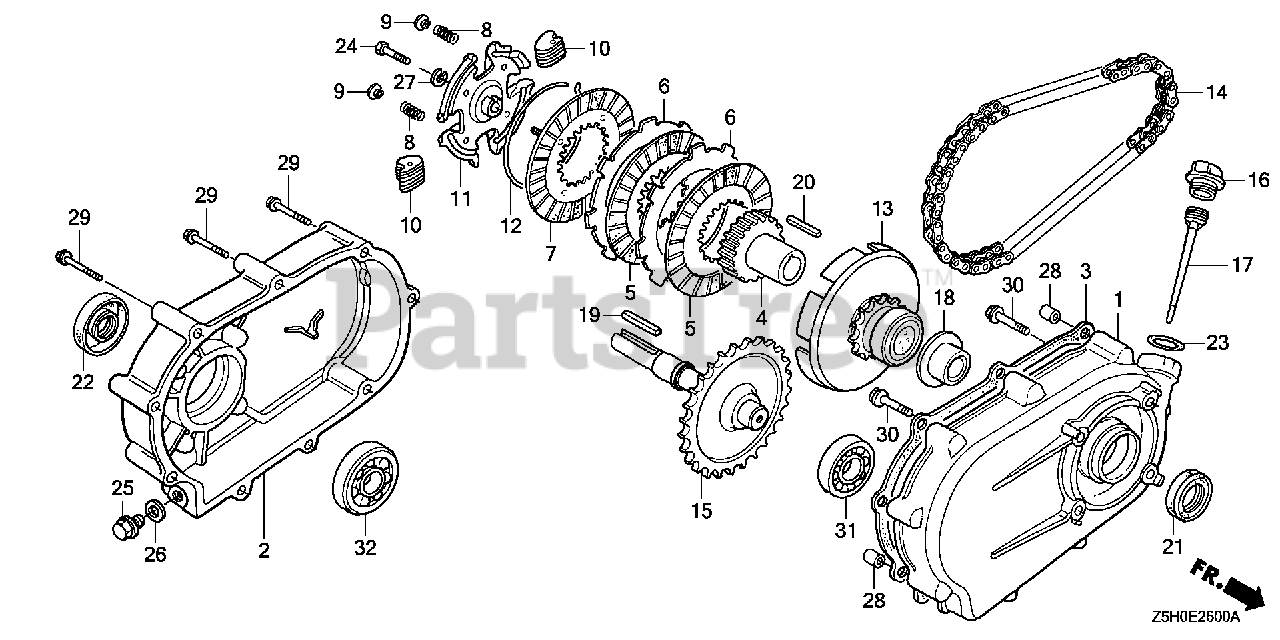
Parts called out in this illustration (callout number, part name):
1	CASE, REDUCTION
2	COVER, REDUCTION
3	GASKET, REDUCTION COVER
4	CENTER, CLUTCH
5	DISK, CLUTCH FRICTION
6	PLATE, CLUTCH
7	PLATE, CLUTCH PRESSURE
8	SPRING, CLUTCH FREE
9	HOLDER, CLUTCH SPRING
10	WEIGHT, CLUTCH
11	HOLDER, CLUTCH WEIGHT
12	CENTER, CLUTCH WEIGHT
13	SPROCKET, DRIVE (14T)
14	CHAIN, DRIVE (RK428SH-36LE)
15	SHAFT, P.T.O. (28T)
16	CAP, REDUCTION OIL (GRAY)
17	DIPSTICK, OIL
18	WASHER, THRUST (25MM)
19	KEY (7X7X33)
20	KEY, CLUTCH CENTER
21	OIL SEAL (30X46X8)
22	OIL SEAL (30X50X7)
22	OIL SEAL (PJ30507)
23	O-RING (26X2.7)
24	BOLT, HEX. (8X35)
25	BOLT, DRAIN PLUG (12MM)
26	WASHER, DRAIN PLUG (12MM)
27	WASHER, SPRING (8MM)
28	PIN A, DOWEL (8X14)
29	BOLT, FLANGE (6X50)
30	BOLT, FLANGE (8X32)
31	BEARING, RADIAL BALL (6205)
32	BEARING, RADIAL BALL (6206)
